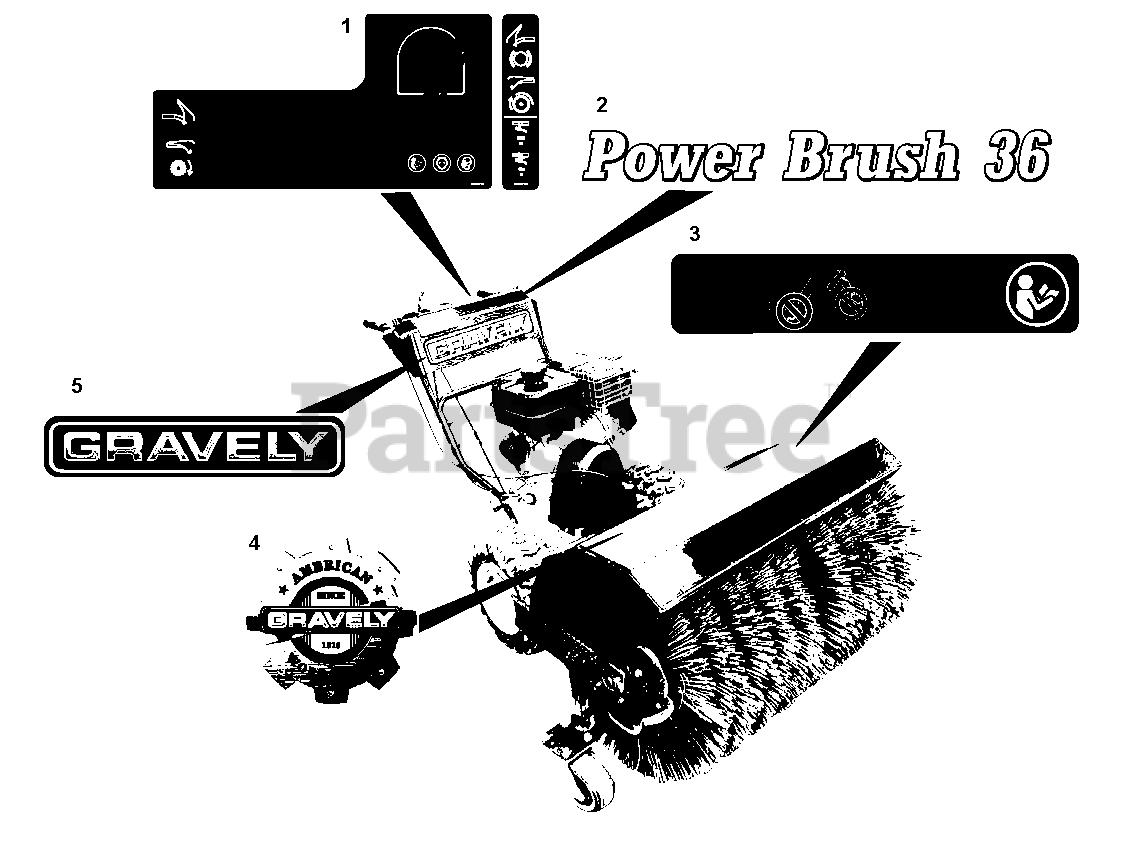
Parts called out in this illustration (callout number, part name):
1	Decal, Control
2	Decal, Power Brush 36"
3	Decal, Danger
4	Decal, Gravely Heritage
5	Decal, 15" Gravely Logo
